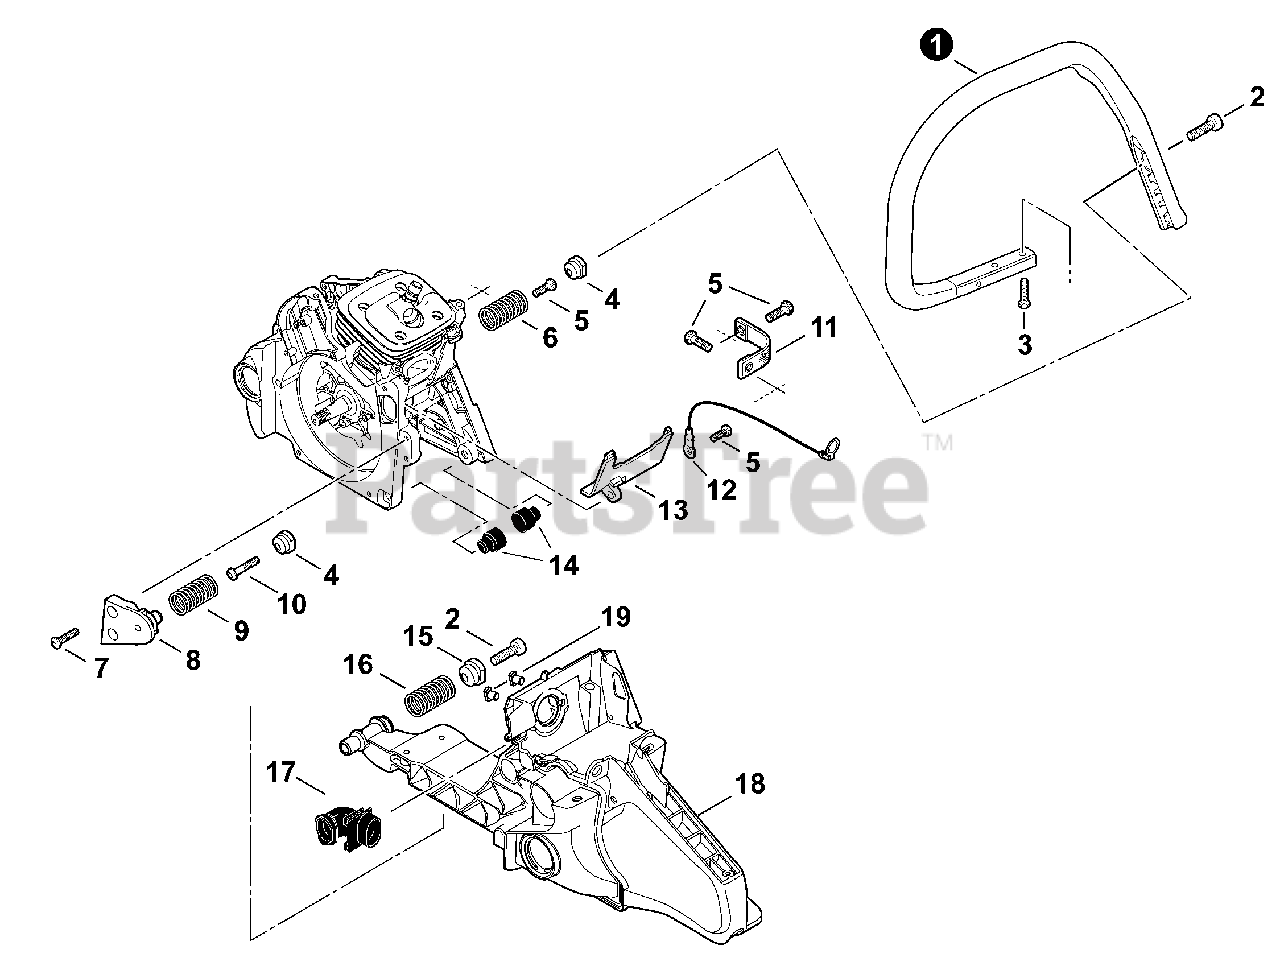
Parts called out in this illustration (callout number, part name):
1	HANDLE, FRONT
2	BOLT, TORX 6×20
3	BOLT, TORX 5×20
4	HOLDER, SPRING Ø14.4
5	BOLT, TORX 5×16
6	SPRING, COMPRESSION Ø17×38.4×2.6
7	BOLT, TORX 5×20
8	HOLDER, SPRING
9	SPRING, COMPRESSION Ø17×36.7×2.6
10	BOLT, TORX 5×25
11	STRAP, SAFETY
12	LEAD - GROUND L= 170
13	GUIDE, AIR
14	CUSHION
15	HOLDER, SPRING Ø17
16	SPRING, COMPRESSION Ø20×40×3.3
17	PIPE, AIR INTAKE
18	HANDLE, REAR
